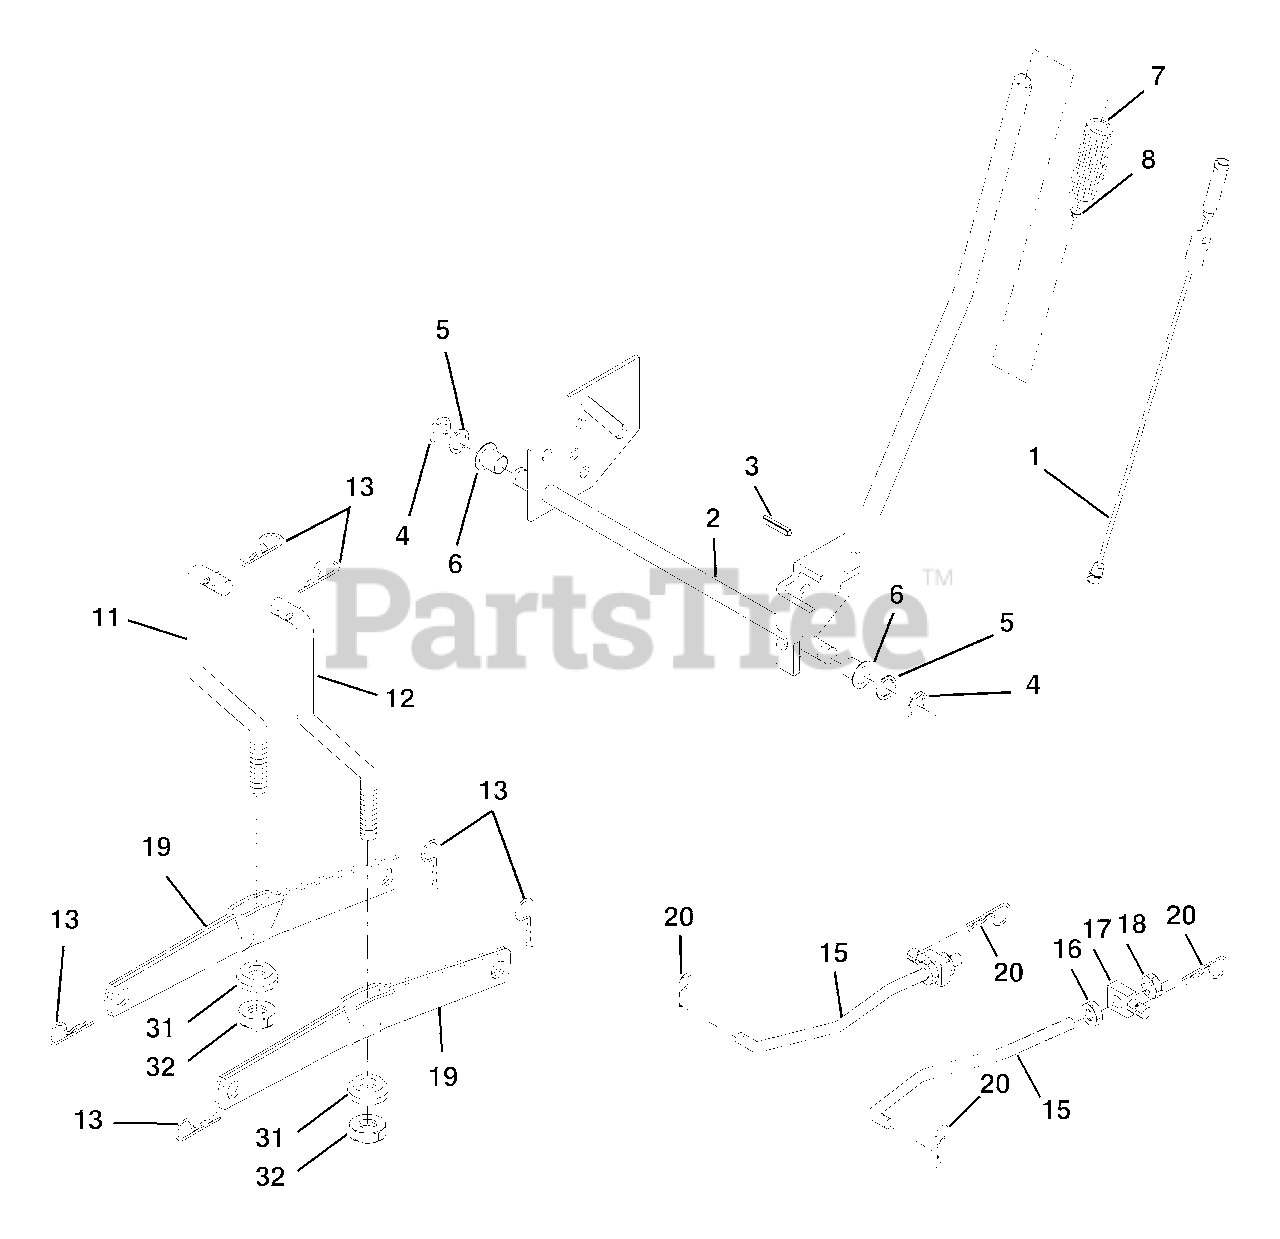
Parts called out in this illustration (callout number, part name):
1	Wire Asm Inner/Sprg w/plunger
2	Shaft Asm Lift RH
3	Pin Groove 1 500 Zinc
4	E Ring #5133-62
5	Washer 21/32 x 1 x 21 Ga.
6	Bearing Nylon Blk 629 Id
7	Grip Handle Bicycle Matte Blk
8	Button Plunger Black
11	Link Lift LH Fixed Length
12	Link Lift RH Fixed Length
13	Retainer Spring
15	Link Front
16	Nut Jam Hex 1/2-13 unc
17	Trunnion
18	Nut Lockw/Wsh 1/2-13 unc
19	Arm Suspension Rear
20	Retainer, Spring
31	Bearing Pvt Lift
32	Nut Crownlock 3/8-24
